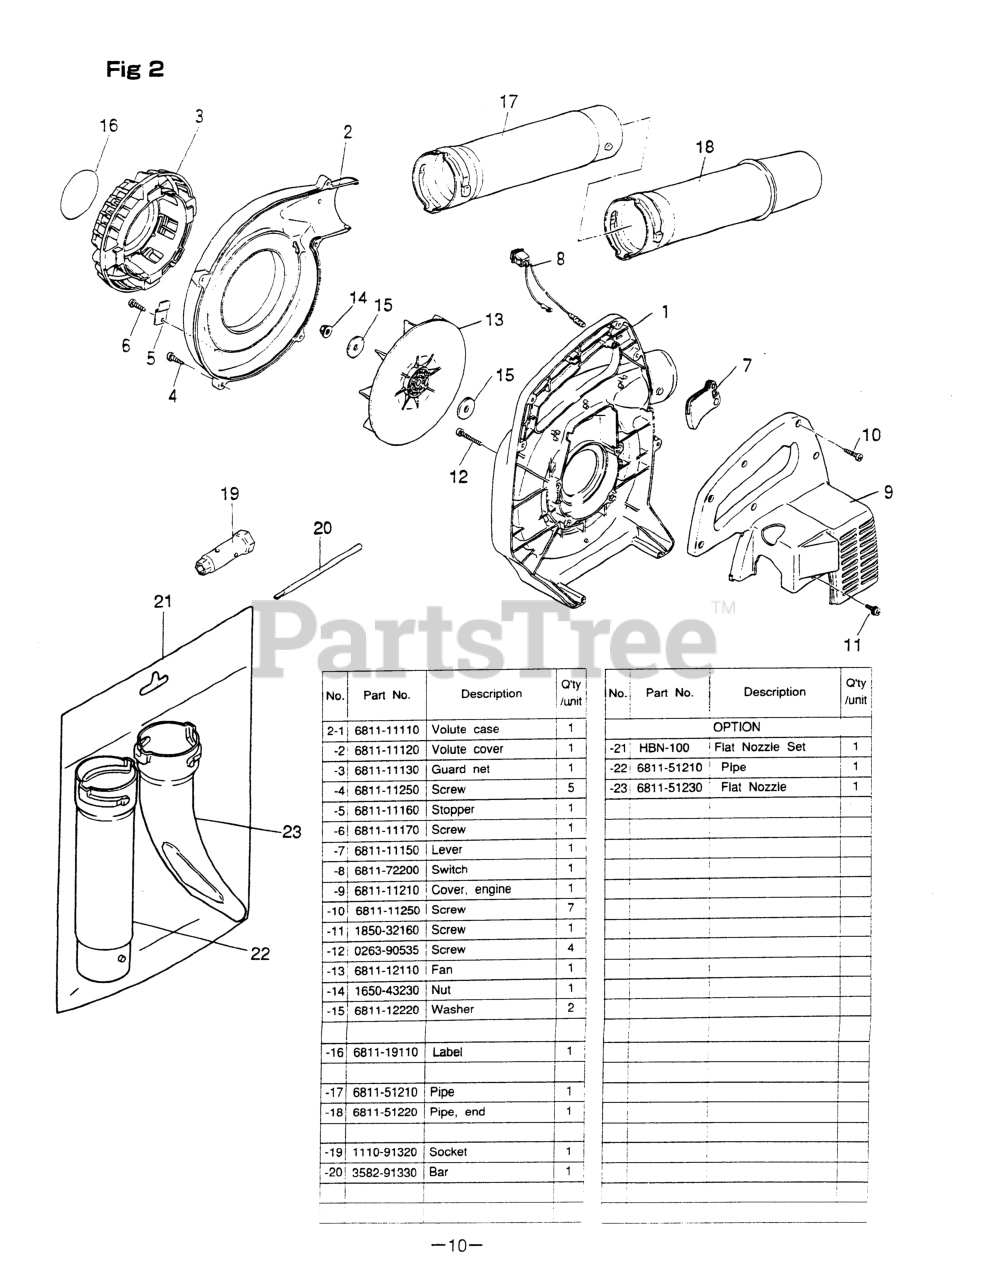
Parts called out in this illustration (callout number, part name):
1	848-L0F-55A1
2	COVER, VOLUTE
3	GUARD
4	SCREW
6	SCREW
7	LEVER
8	SWITCH
9	COVER
10	SCREW
11	SCREW, M5 x 12
12	SCREW, M5 x 35
13	FAN
15	WASHER
16	LABEL
18	PIPE, END
19	SOCKET, HEX, 3/4
21	FLAT NOZZLE SET
23	NOZZLE, FLAT
